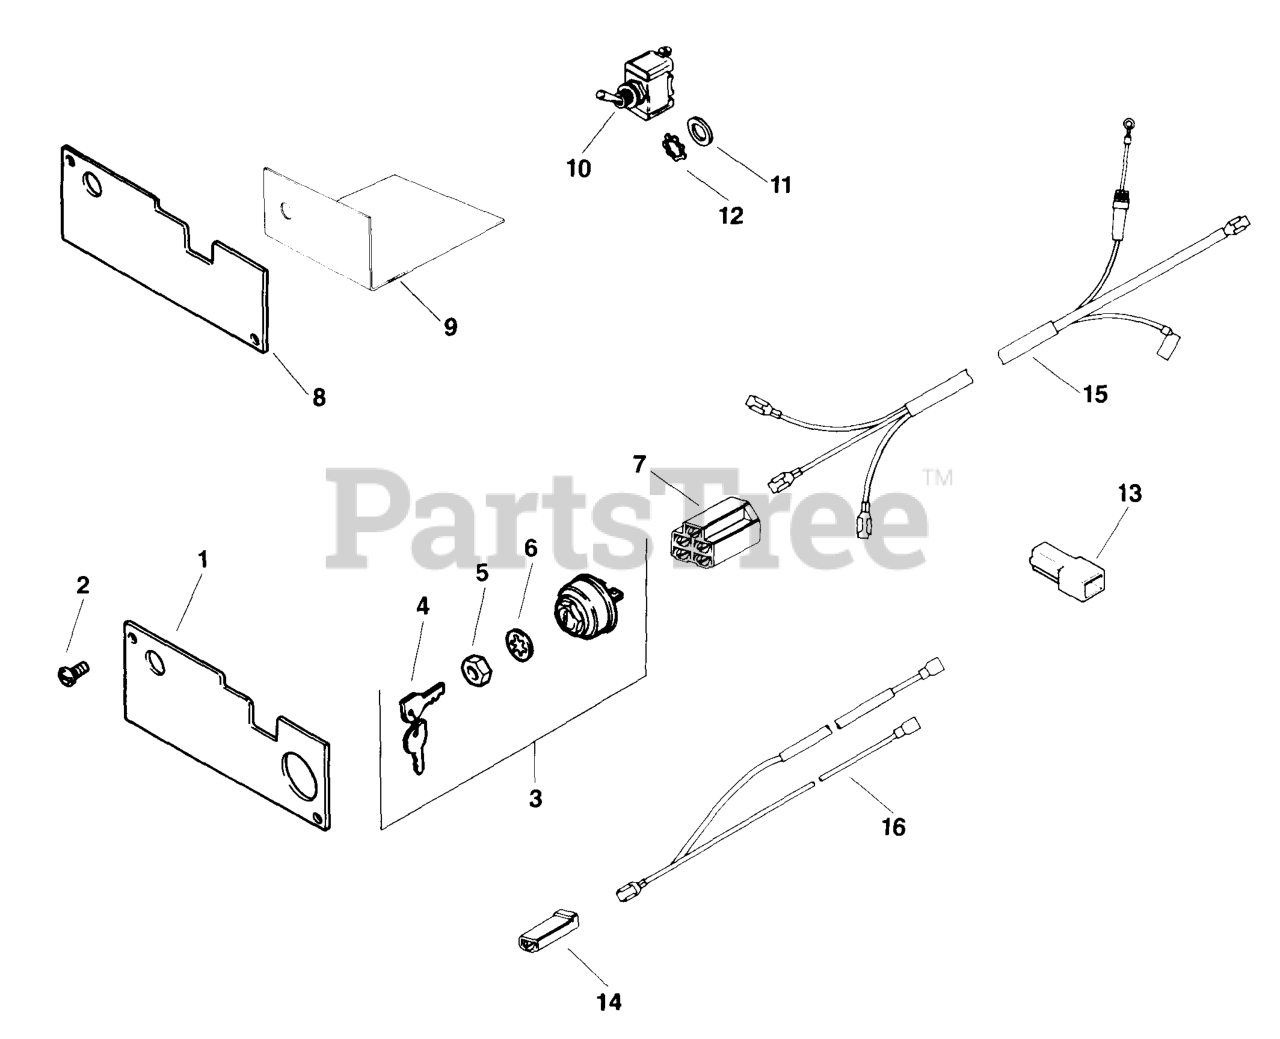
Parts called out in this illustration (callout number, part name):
1	PANEL - DISCONTINUED
2	SCREW - DISCONTINUED
3	SWITCH ASSY, KEY (KM)-USE 25 099 32-S
4	KEY, SET -USE 48 340 01-S
5	NUT, KEY SWITCH
6	WASHER, INTERNAL TOOTH
7	CONNECTOR
15	HARNESS
16	HARNESS - DISCONTINUED
